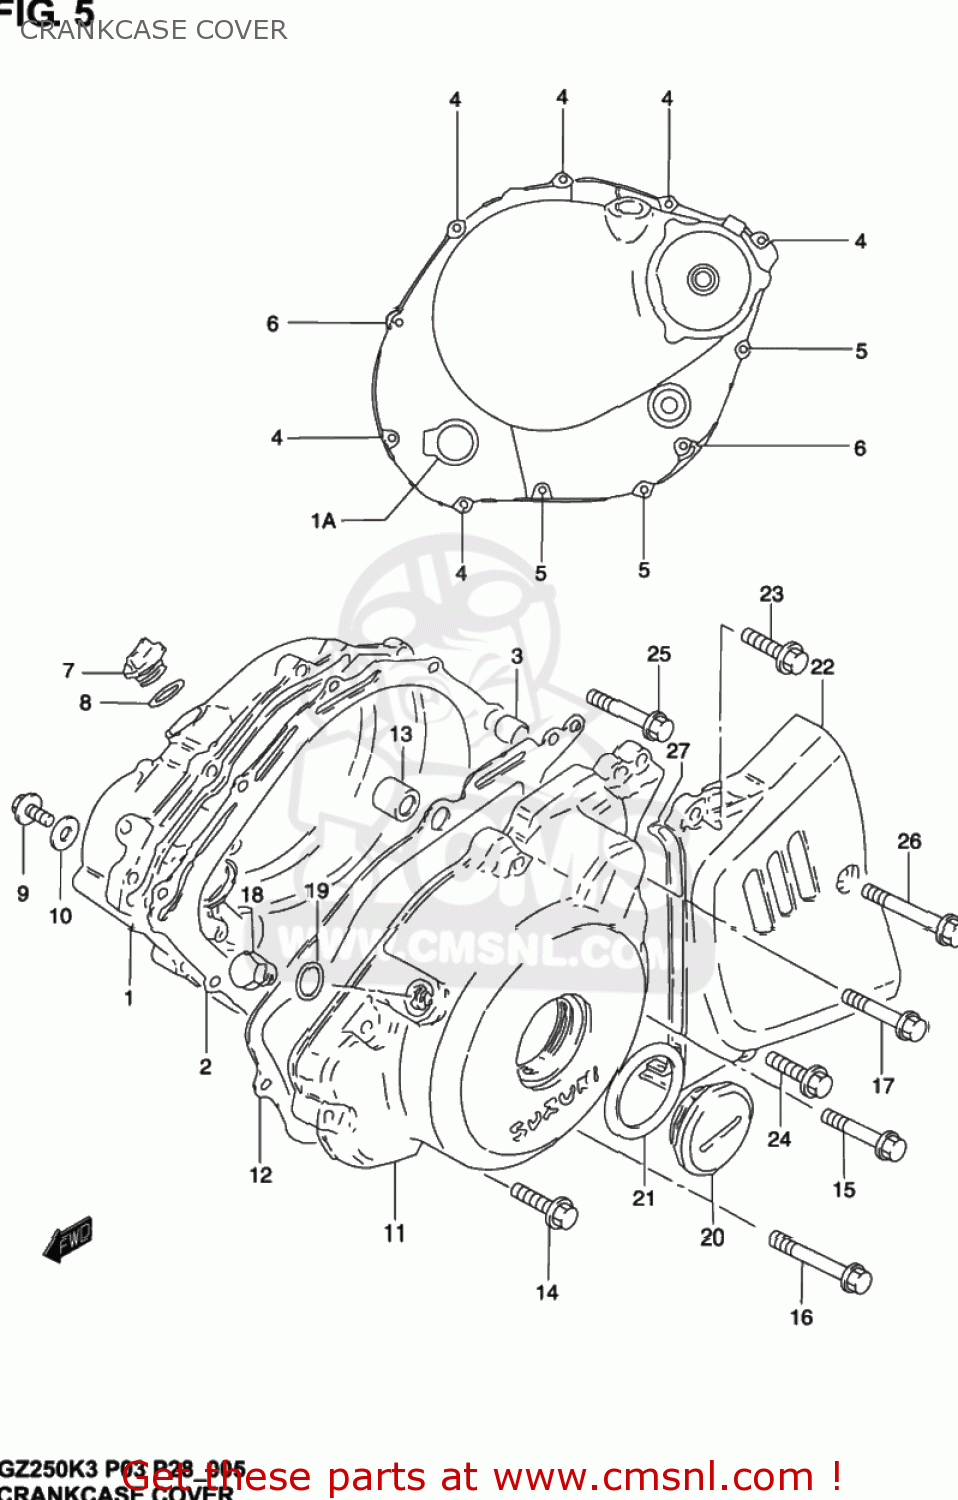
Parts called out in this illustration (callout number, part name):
1	COVER,CLUTCH
1A	LENS,OIL LEVEL CHECK
2	GASKET,CLUTCH COVER (NAS)
3	PIN
4	BOLT
5	BOLT
6	BOLT
7	PLUG(20X10)
8	O RING(D:3.1,ID:16.8)
9	PLUG (14X12)
10	GASKET(13.8X18.8X4.8) (NAS)
11	COVER,MAGNETO
12	GASKET,MAGNETO COVER (NAS)
13	PIN
14	BOLT
15	BOLT
16	BOLT
17	BOLT
18	PLUG,12X9
19	GASKET(12.1X16.2X3.7) (NAS)
20	PLUG,36X10
21	O RING(D:3.1,ID:32.7)
22	COVER,ENGINE SPROCKET
23	BOLT
24	BOLT
25	BOLT
26	BOLT
27	DAMPER,ENGINE SPROCKET COVER
